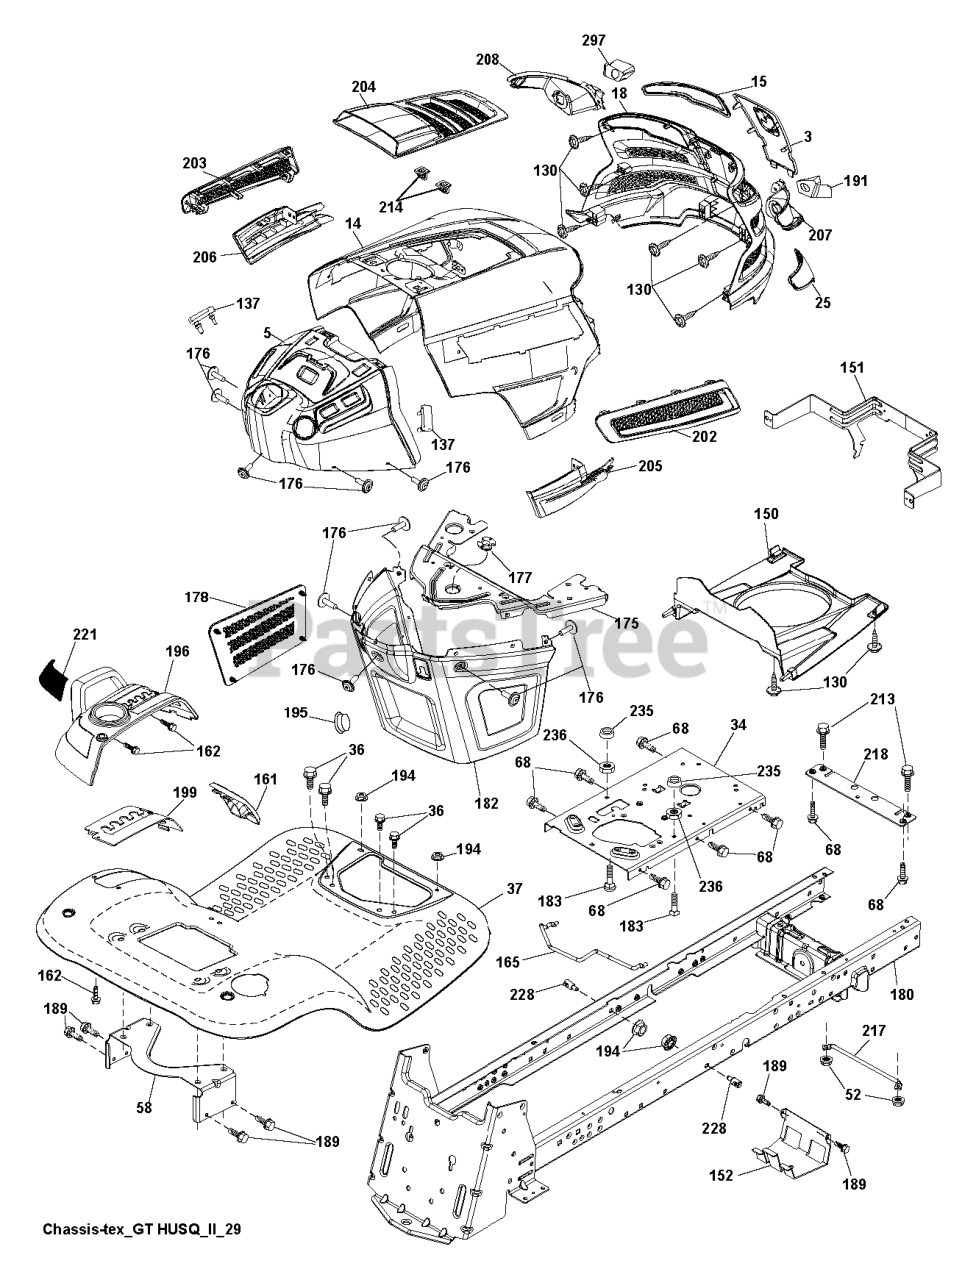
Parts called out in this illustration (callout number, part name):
3	APPLIQUE.SUBASM.GT.HUSQ.II
5	DASH.UPP.GT2.SM.PTO.MCHOKE
14	HOOD.ASM.HUSQVARNA.GT.TEX.ORAN
15	LENS.HEADLIGHT.LH.GTII.2011
18	GRILLE.SUBASM.GT.HUSQ.II
25	LENS.HEADLIGHT.RH.GTII.2011
34	PLATE.ENGINE.WELDED.CHASSIS
36	SCREW 5/16"
37	FENDER.PNT.TX.GT.CH/FW/DL.HUSQ
52	LOCKNUT
58	BRKT.SUPPORT.FNDR/TANK
68	Screw 5/16-18 x 1/2 Hex, Self Tapping 5/16-18 x 1/2
130	SCREW.#10 X 0.750.BOS
137	BUMPER DASH
150	AIR.DUCT.GTV.BLACK
151	BRACKET.PIVOT.HOOD.GT.HUSQ.II
152	SHIELD.BROWNING.W/TEX
161	CONSOLE.WINDOW.FUEL.HUSQ.GT
162	SCREW.HI-LO.CONSOLE
165	SUPPORT.TANK.REAR.W/TEX
175	PLATE.CROSSMEMBER.HUSQ
176	SCREW.#10-24X5/8.RN.QU
177	BUSHING, STEERING
178	CARGO.ASM.NET.TXGT.W/C
180	CHASSIS.GT.SLOPED.DRAWBAR.
182	DASH.LOWER.COMMON.12V.ADAPTOR
183	BOLT.5/16-18X1-1/4 FULL THD
189	SCREW
191	INSERT.REFLECTIVE.RH.HUSQ.GTII
194	NUT LOCK HEX FLANGE 5/16-18
195	PLUG.HOLE.DASH.LOWER.12V.BLK
196	SUBASM.CONSOLE.HUSQ.GT.DECKLFT
199	PLATE.DECK.LIFT.HUSQVARNA.GT
202	VENT.SIDE.RH.GT.HUSQ.II.
203	VENT.SIDE.LH.GT.HUSQ.II.498
204	VENT.TOP.HUSQ.GT2
205	SIDE.TRIM.RH.GT.HUSQ.II
206	SIDE.TRIM.LH.GT.HUSQ.II.GRAY
207	BEZEL LIGHT.RH.GT.II.MYLAR
208	BEZEL LIGHT.LH.GT.II.MYLAR
213	BOLT
214	CLIP.RETAINER.TINNER.
217	ROD.PIVOT.HOOD
218	X-PIECE.HOOD.STOP.NON/
221	REFLECTOR.LH.TEX GT HU
228	STUD.FASTNER.W/ANTI-ROTATE
235	SPACER FENDER
236	NUT.CENTERLOCK.5/16-
297	INSERT.REFLECTIVE.LH.HUSQ.GTII
